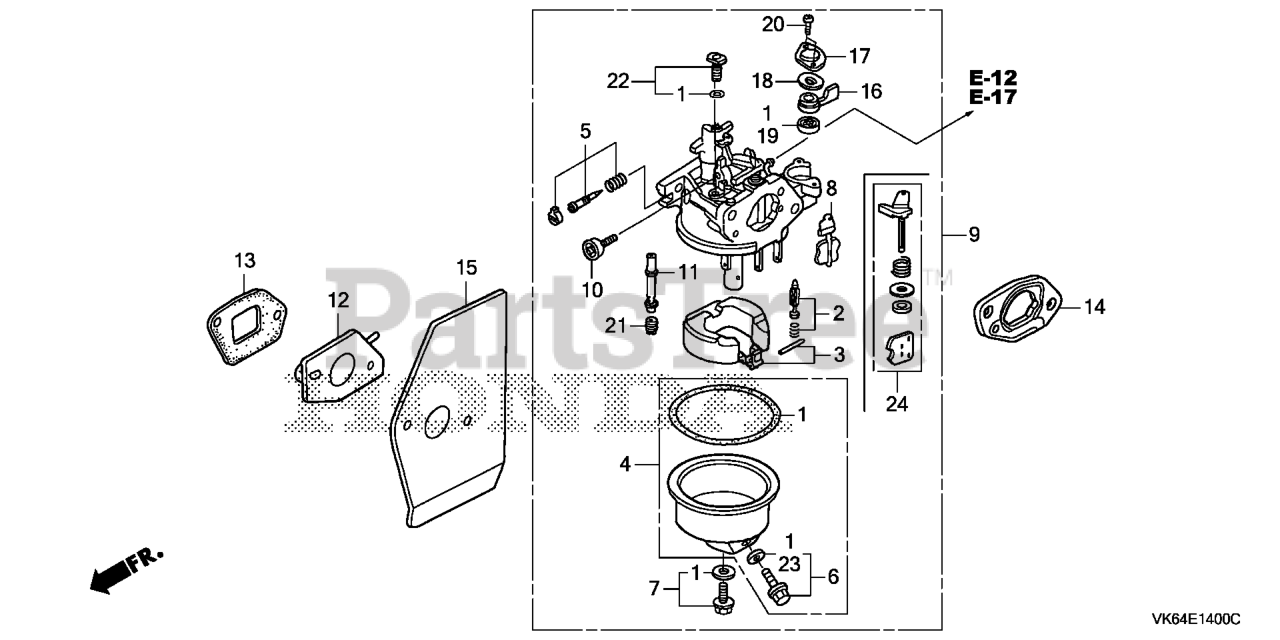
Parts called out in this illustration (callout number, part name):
1	GASKET SET
2	VALVE SET, FLOAT (CARBURETOR NO.) (SEAT NOT INCLUDED)
3	FLOAT SET
4	CHAMBER SET, FLOAT
6	SCREW SET, DRAIN
9	CARBURETOR ASSY. (BEA2T A)
10	SCREW, THROTTLE STOP
11	NOZZLE, MAIN
12	INSULATOR, CARBURETOR
13	GASKET, INSULATOR
13	GASKET, INSULATOR (NINGBO SIL GASKET)
14	SPACER, CARBURETOR
15	GASKET, CARBURETOR
15	GASKET, CARBURETOR (NINGBO SIL GASKET)
16	LEVER, PETCOCK
17	PLATE, LEVER SETTING (CARBURETOR NO.)
18	SPRING, PETCOCK LEVER (CARBURETOR NO.)
19	GASKET, VALVE
20	SCREW, PAN (3X6)
21	JET, MAIN (#60)
21	JET, MAIN (#62)
21	JET, MAIN (#65)
22	JET SET, PILOT (#40) (ADVENTURE GREEN) (CARBURETOR NO.)
23	WASHER, PLAIN (6.2X10.7 DRAIN) (CARBURETOR NO.)
